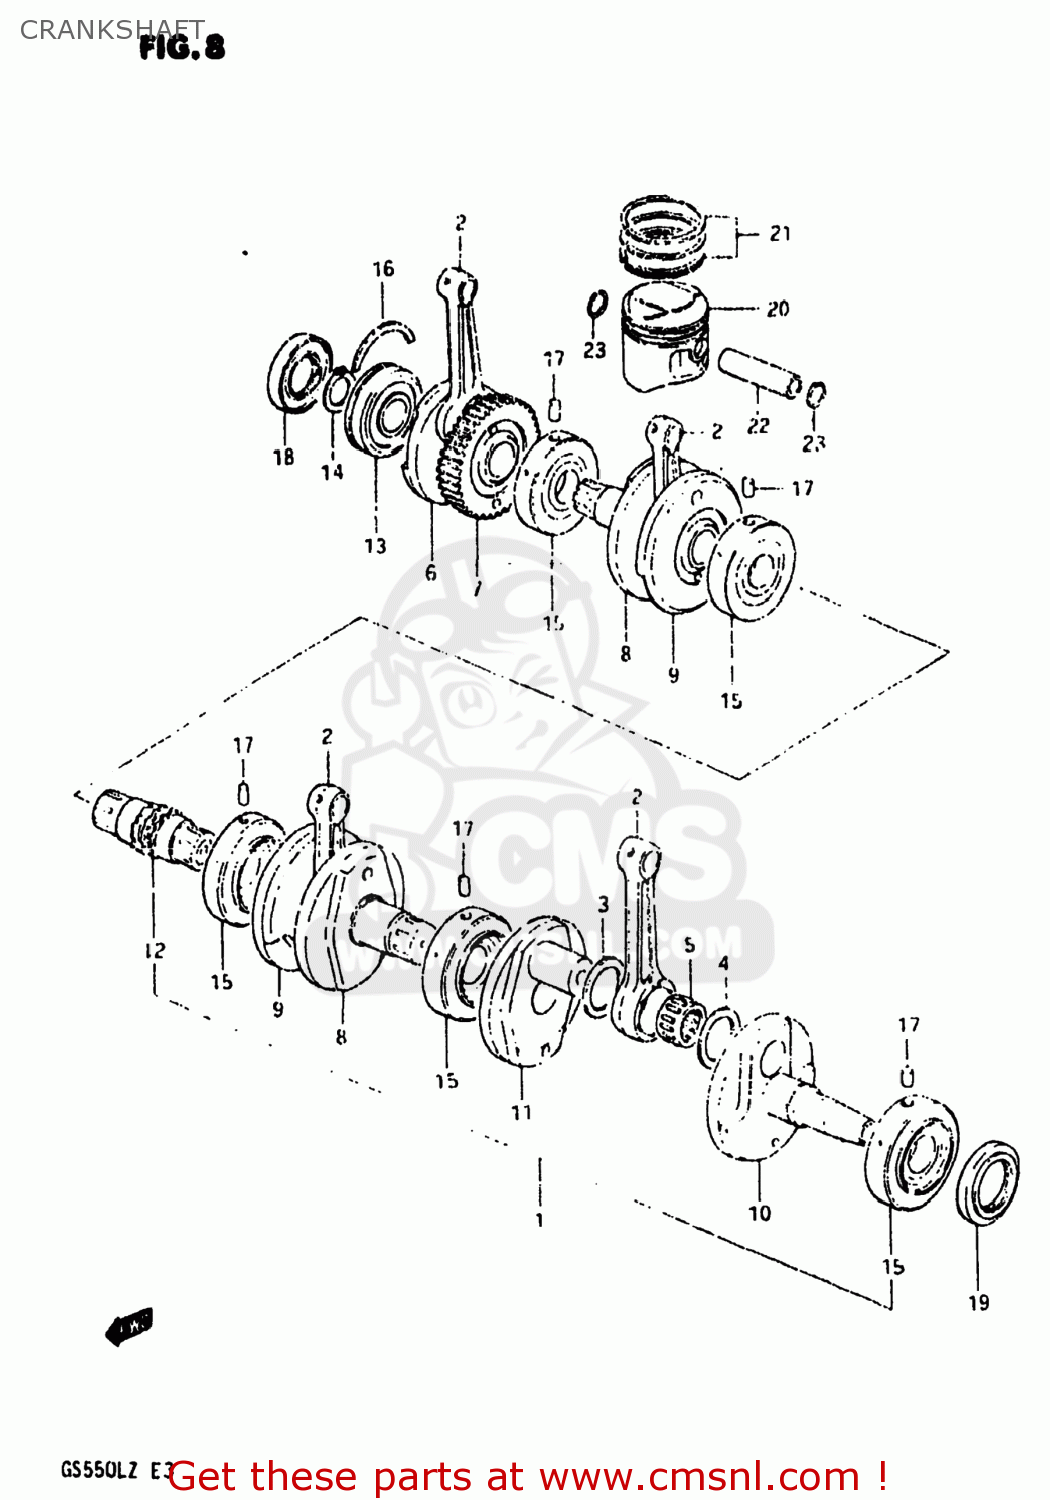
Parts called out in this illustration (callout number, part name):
1	CRANKSHAFT ASSEMBLY
2	ROD,CONNECTING
3	WASHER (28X48X2)
4	WASHER(28X48X1)
5	ROLLER BEARING (28X38X16.8)
6	CRANKSHAFT
7	WEB,CRANK
8	CRANKSHAFT
9	WEB,CRANK,MIDDLE
10	CRANKSHAFT,LEFT
11	WEB,CRANK,LEFT
12	SHAFT,TIMING CHAIN DRIVE
13	BEARING(30X72X19)
14	CIRCLIP,30MM
15	BEARING
16	C RING
17	PIN
18	SEAL,OIL(30X72X11)
19	OIL SEAL
20	PISTON
21	RING SET,PISTON
22	PIN,PISTON 16MM
23	CIRCLIP
